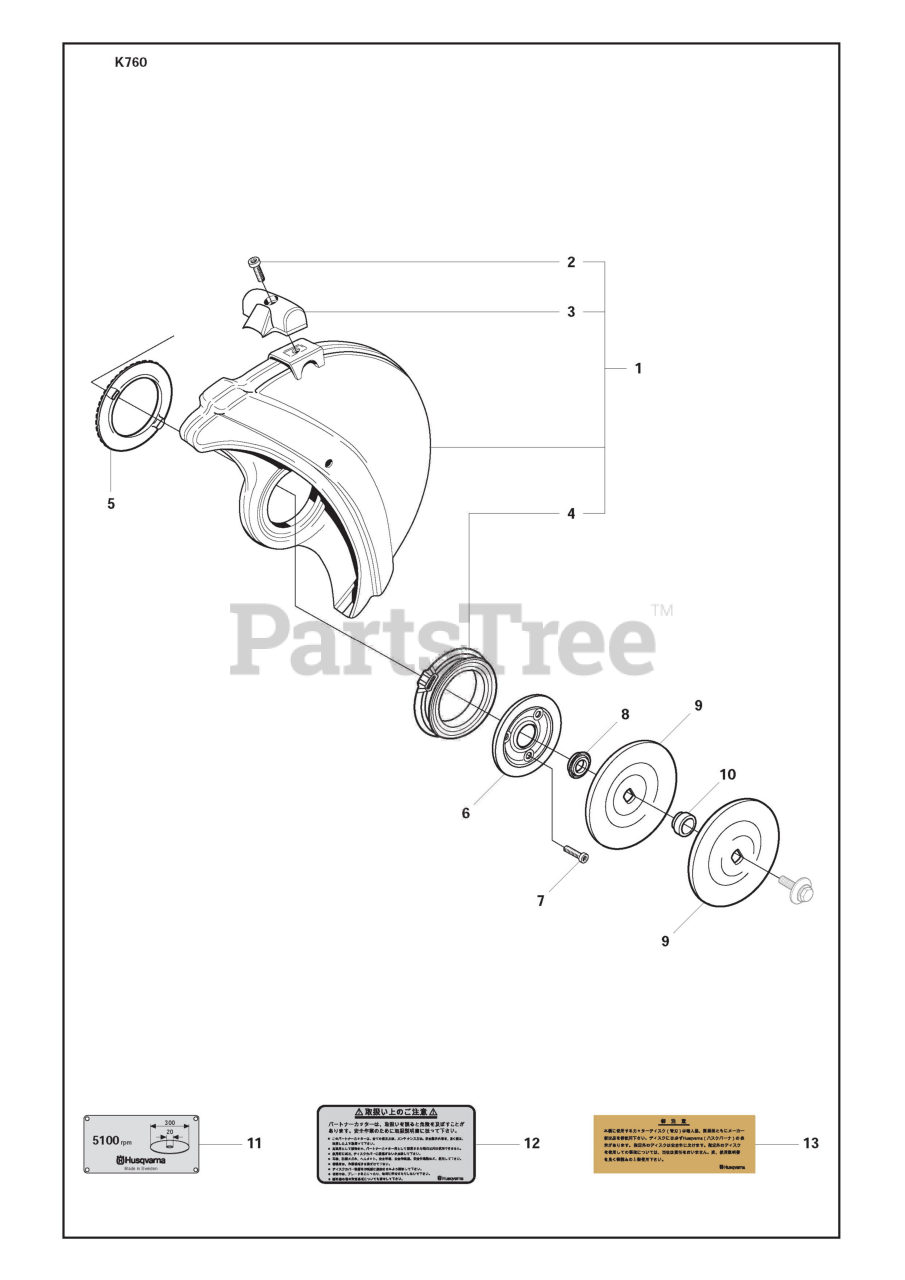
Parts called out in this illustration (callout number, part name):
1	Wheel Guard Assy
5	Screen Pattern Flang
8	Support Flange
9	Flange Washer
10	Bushing
11	Label
12	Label
13	Label
